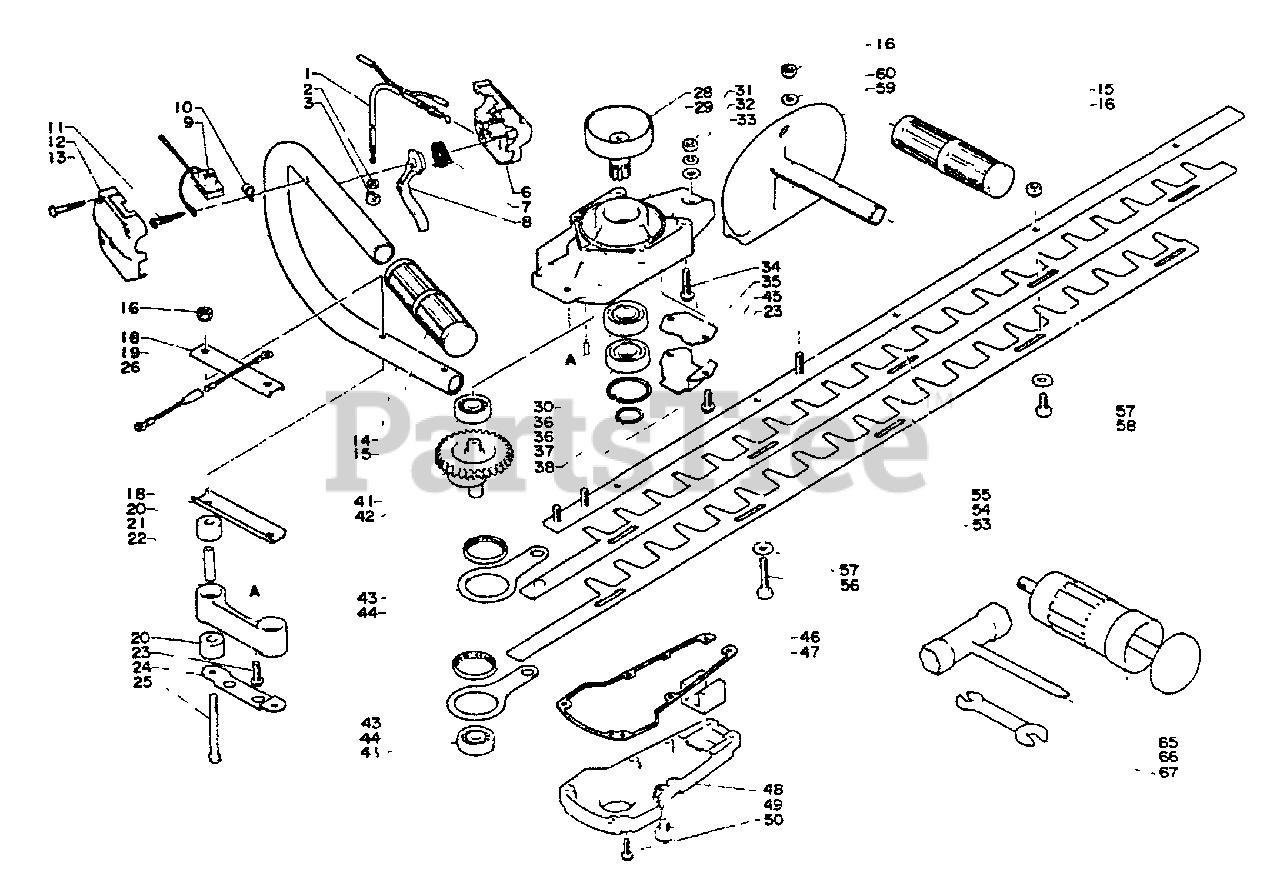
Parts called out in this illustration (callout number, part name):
1	CABLE, THROTTLE
6	BRACKET, THROTTLE CONTROL - RIGHT
7	SPRING, THROTTLE RETURN
8	TRIGGER, THROTTLE
9	IGNITION SWITCH ASSY
10	HOLDER
11	SCREW - 4×8
12	BRACKET, THROTTLE CONTROL - LEFT
13	SCREW 4×25
14	HANDLE, REAR
16	LOCKNUT - 5
19	LEAD - GROUND
21	SPACER
22	BRACKET, HANDLE
23	SCREW 5×14
24	PLATE
25	BOLT 5×60
26	LEAD - GROUND
28	DRUM, CLUTCH
29	CASE, GEAR
30	PIN, LOCATING 4
31	NUT, HEX M6
32	WASHER, SPRING 6
33	WASHER 6.5×11.5×0.8
34	SCREW - 5×20
35	GUIDE
36	BEARING, BALL 6200
37	RING, SNAP Ø32
38	RING, RETAINING - 17
41	BEARING, BALL 6003
42	GEAR
43	BEARING, NEEDLE
44	ROD, CONNECTING
45	GUIDE
46	GASKET, GEAR CASE
48	LID, GEAR CASE
49	BOLT 8×8 SP
50	SCREW 4×16
53	TRIMMER BLADE SET
54	TRIMMER BLADE SET
55	FRAME BAR
56	BOLT
57	WASHER
58	BOLT
59	HANDLE, FRONT
60	WASHER, FLAT 5.5×10×0.8
65	PUMP, GREASE
66	T-WRENCH
67	SPANNER 8×10
